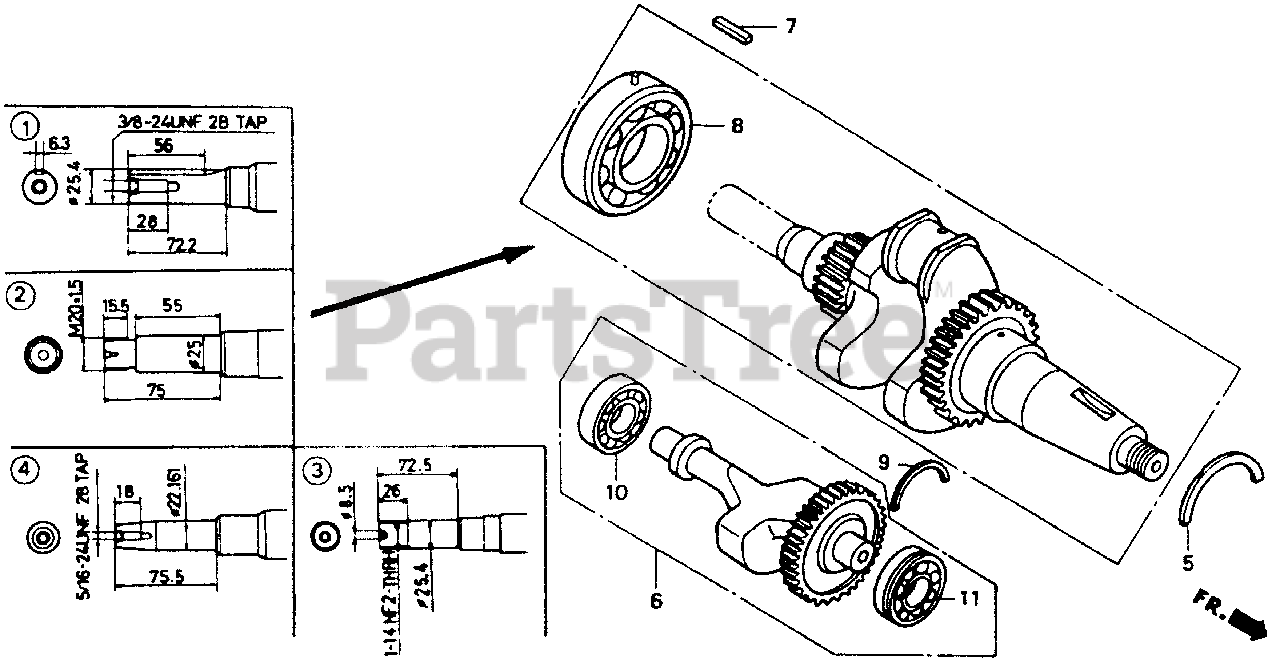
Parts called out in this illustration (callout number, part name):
2	CRANKSHAFT (W-TYPE)
5	BEARING A, CRANKSHAFT THRUST (BLUE)
5	BEARING B, CRANKSHAFT THRUST (BLACK)
5	BEARING C, CRANKSHAFT THRUST (BROWN)
5	BEARING D, CRANKSHAFT THRUST (GREEN)
5	BEARING E, CRANKSHAFT THRUST (YELLOW)
5	BEARING F, CRANKSHAFT THRUST (PINK)
6	WEIGHT, BALANCER
8	BEARING, SPECIAL (6307)
9	SET-RING (470)
10	BEARING B, SPECIAL BALL (6204)
11	BEARING C, SPECIAL BALL (6204)
